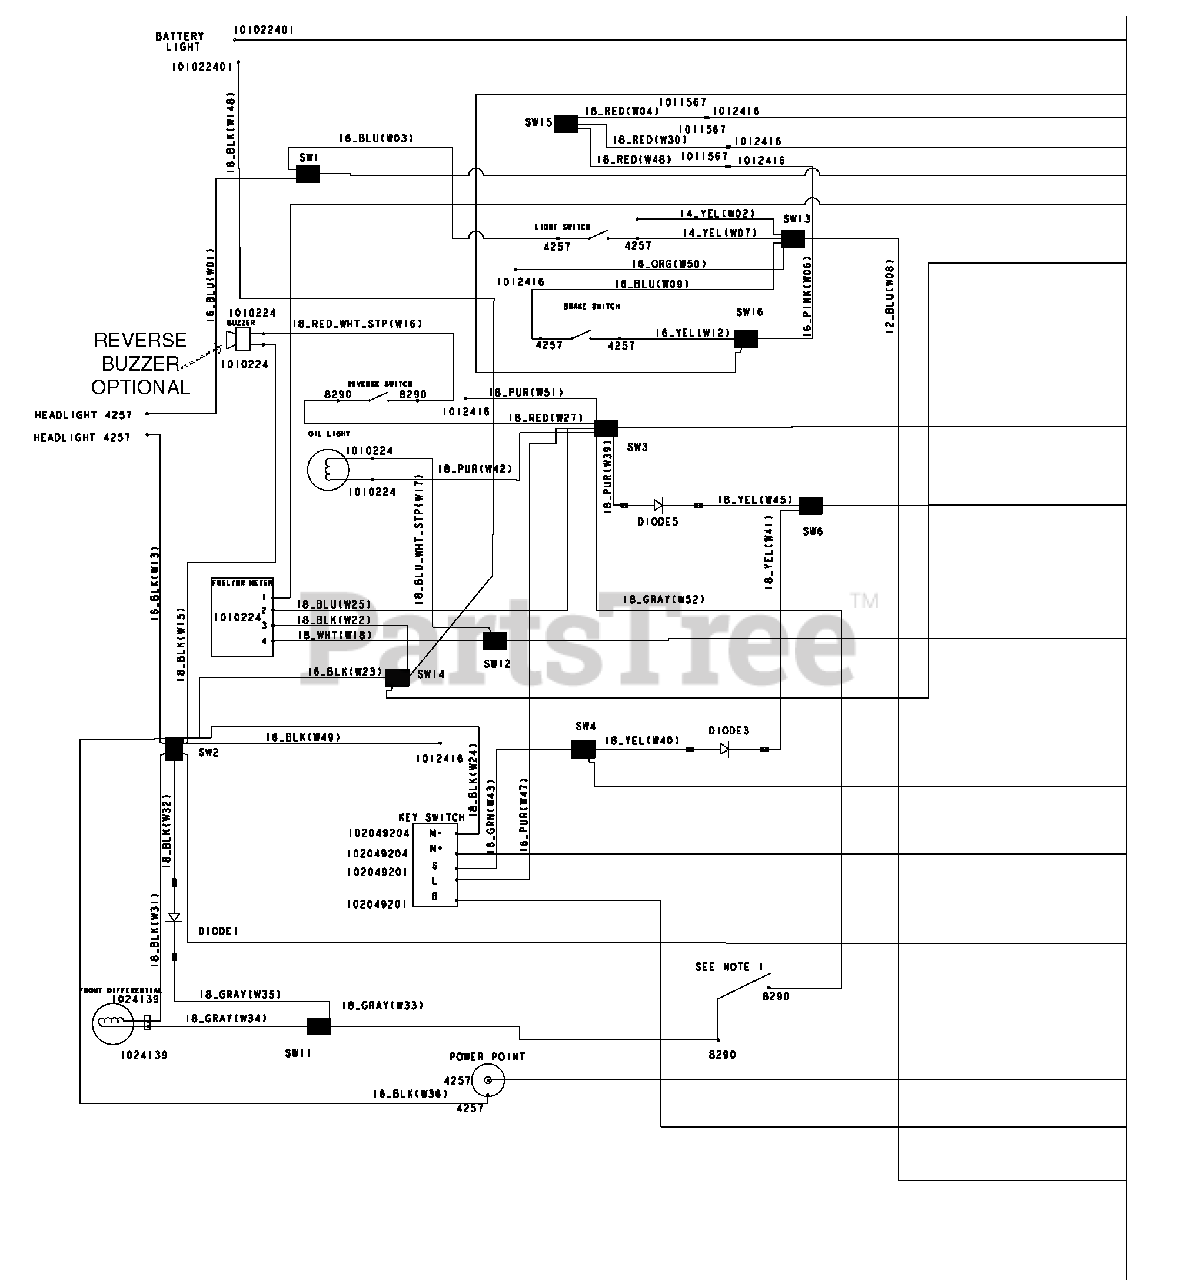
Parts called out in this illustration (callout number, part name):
1	Diode, General Purpose, 6.0a
2	Harness, AWD, Kawasaki
3	Asm, Switch, Limit, Awd
